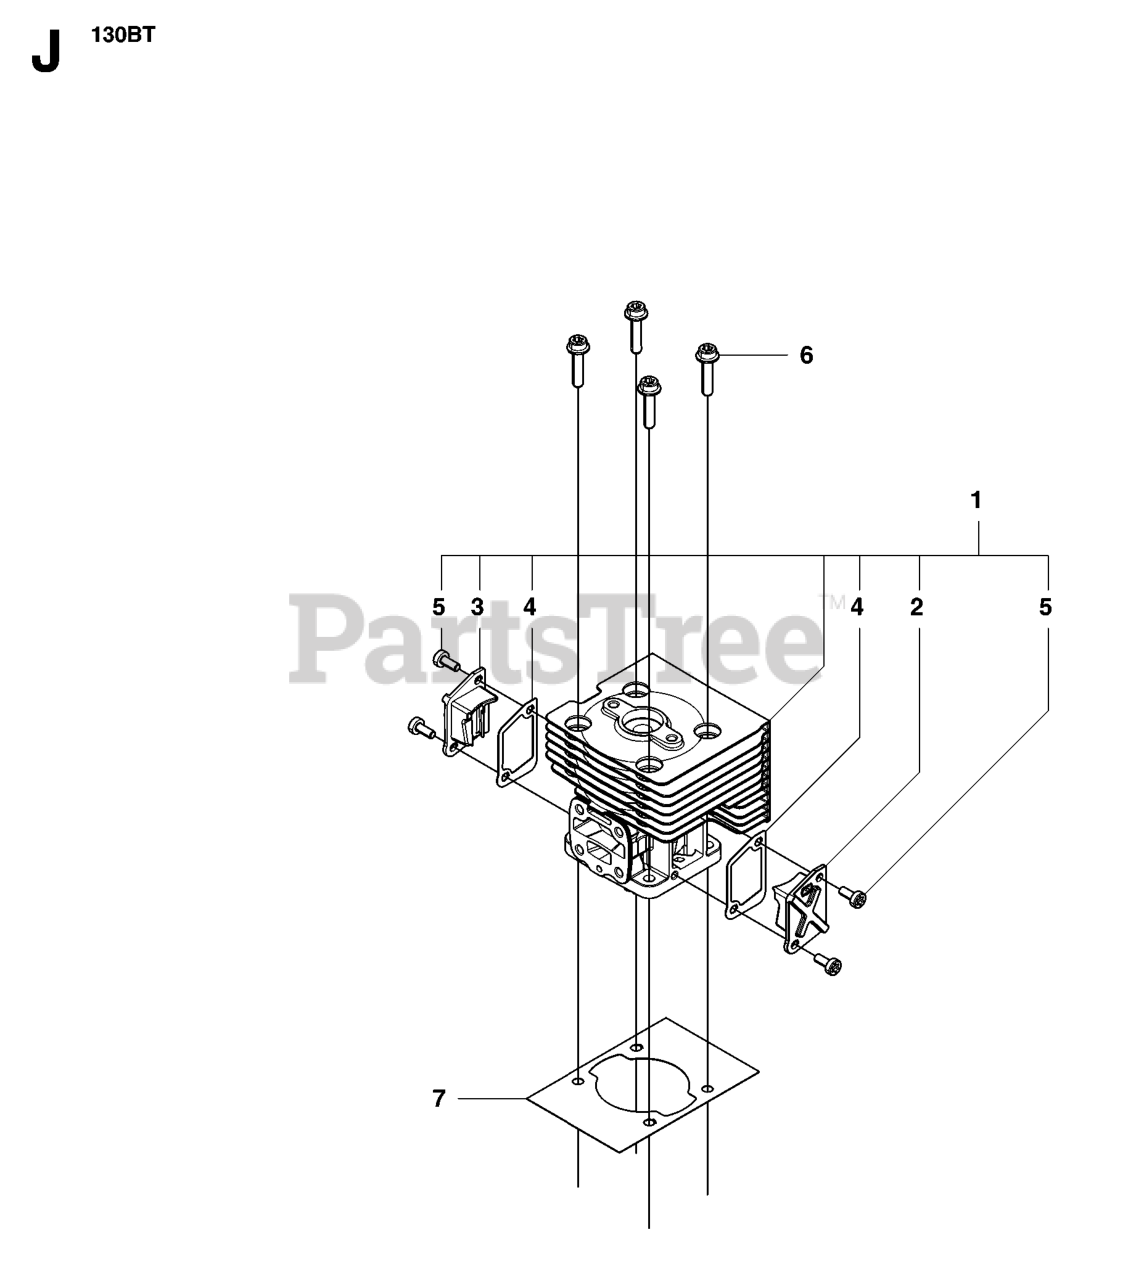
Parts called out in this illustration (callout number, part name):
1	CYLINDER
2	COVER TR(S)
3	COVER TR (F)
6	BOLT
7	GASKET BASE
